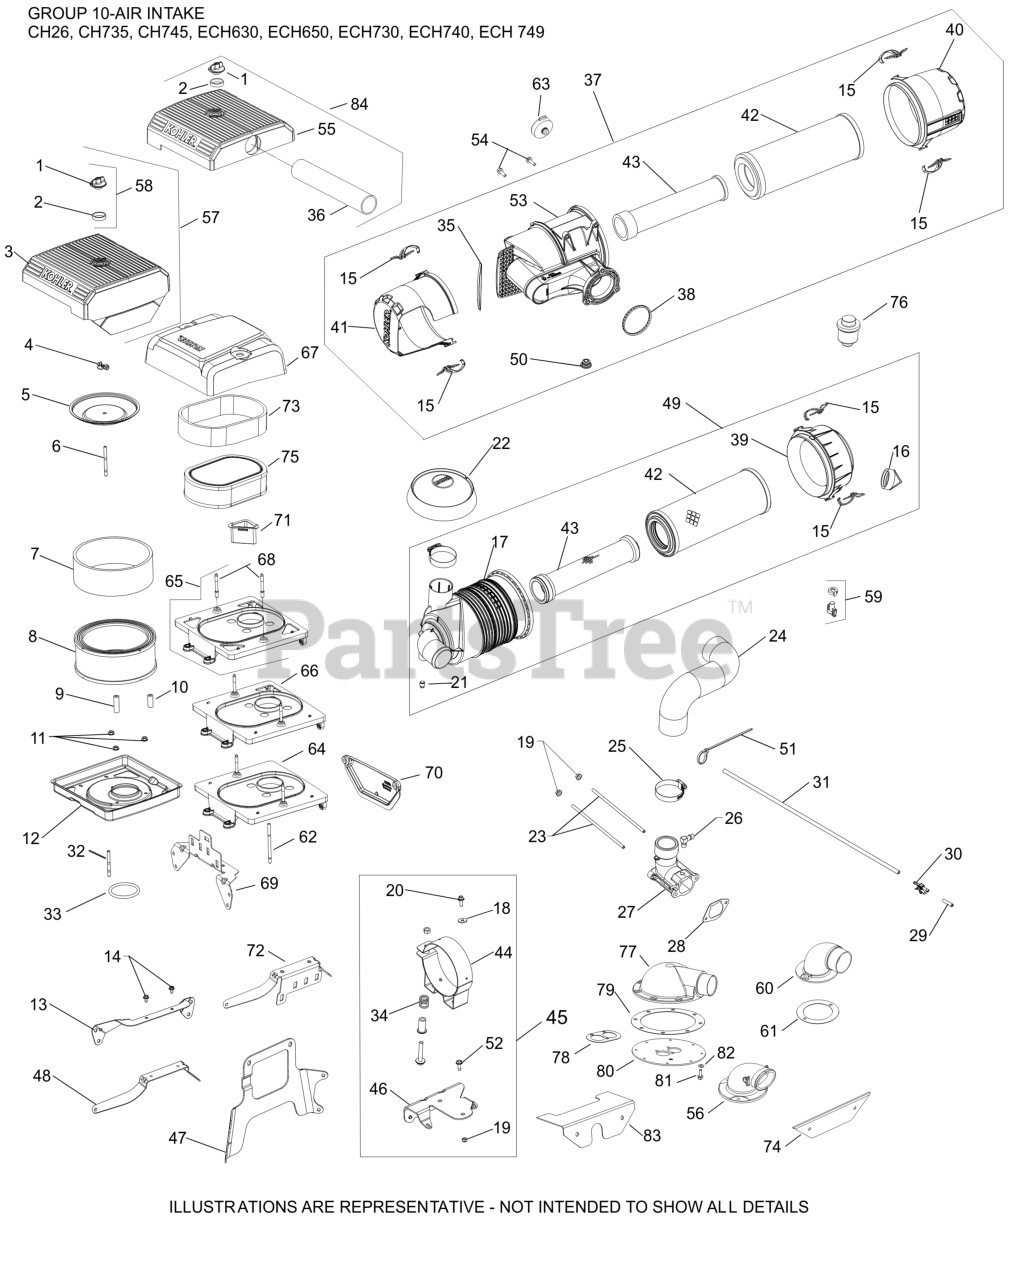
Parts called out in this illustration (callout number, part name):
11	NUT, FLG M6X1.0
12	BASE, AIR CLEANER
29	CAP, MASKING
30	CONNECTOR, EVAPORATIVE
